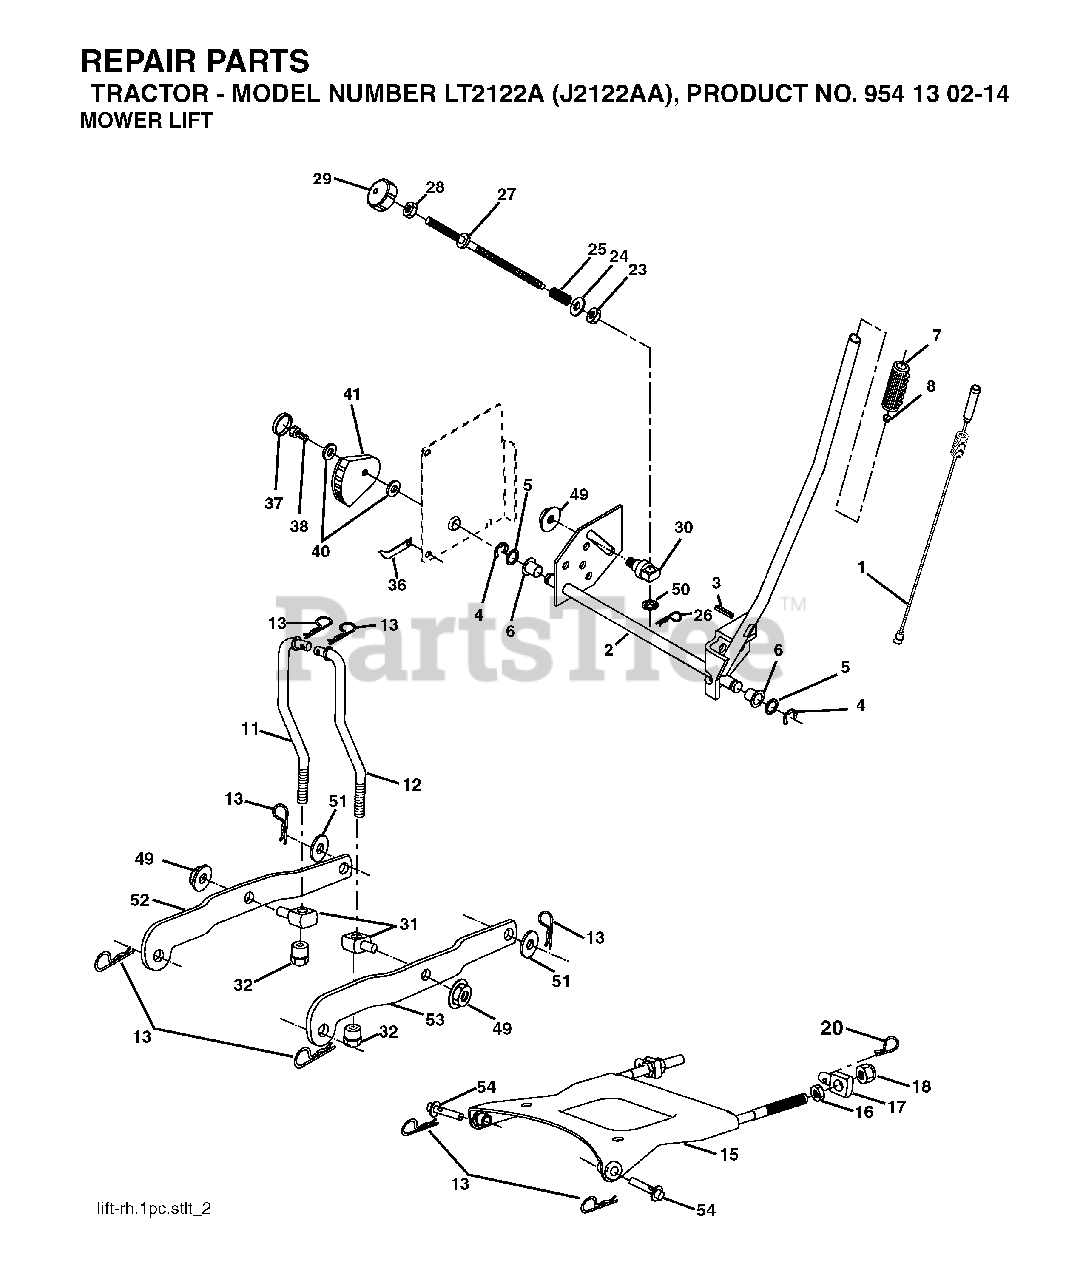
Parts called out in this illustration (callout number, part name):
1	WIRE, INNER
3	PIN GROOVE
4	RETAINING RING LT
6	BEARING.NYLON
7	GRIP HANDLE
11	LIFT LINK LH
12	LIFT LINK RH
13	RETAINER-SPRNG RB
15	PLATE ASM SUSP FRONT
16	NUT
18	NUT
20	SPRING RETAINER
26	RETAINER CLIP
28	NUT
29	KNOB INF 3/8-16
32	NUT, LIFT LINK 7/16-20
36	POINTER, HEIGHT INDICATOR
37	PLUG,HOLE
38	SCREW 5/16-18X1
41	IND. HEIGHT STLT
49	NUT
50	NUT PUSH M
52	ARM SUSP. REAR LH
53	ARM SUSP REAR RH
54	PIN, FLANGE
